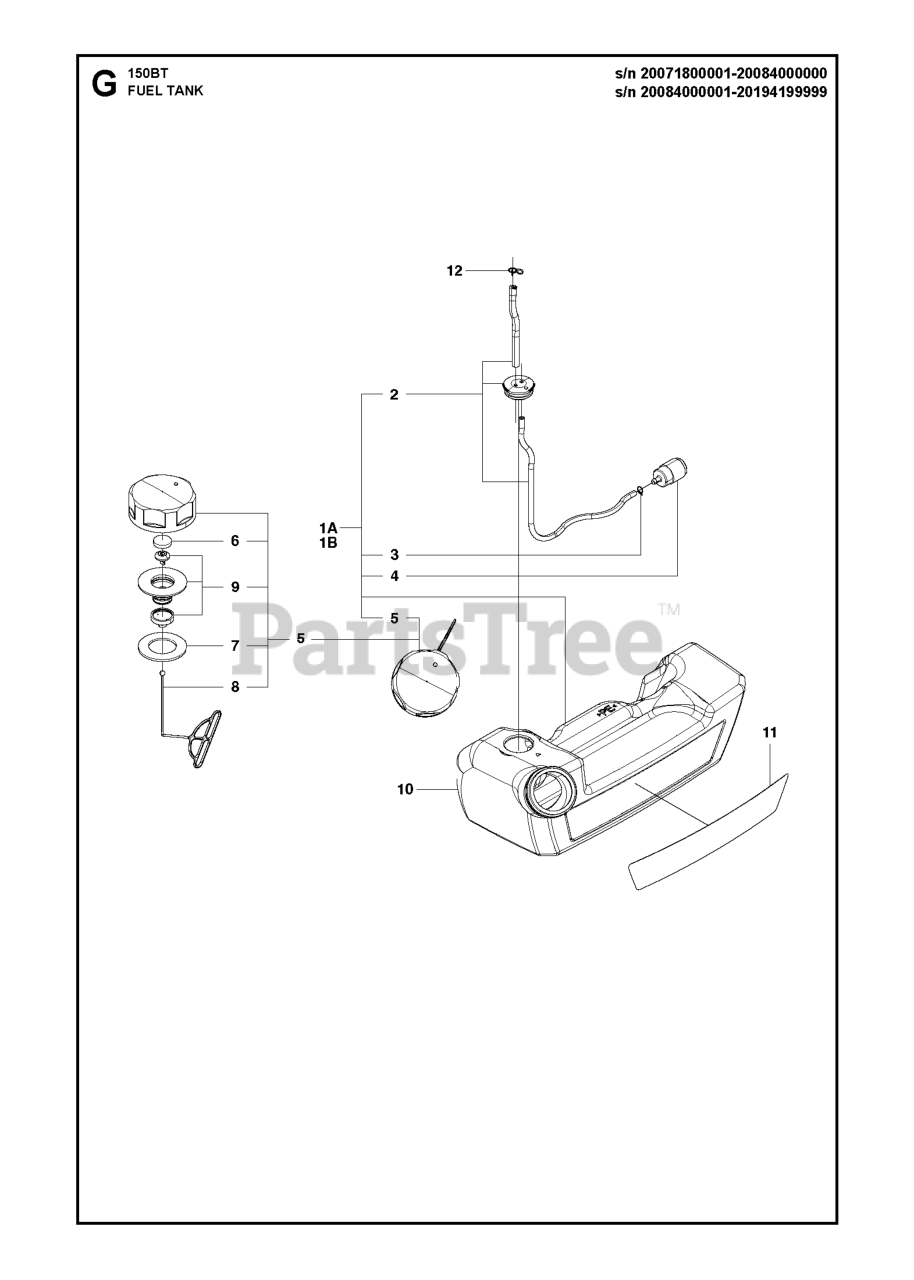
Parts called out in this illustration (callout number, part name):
1A	TANK ASSY
1B	TANK ASSY
2	PIPE C
3	CLIP
4	FILTER
5	ASSY FUEL CAP
6	FILTER
7	PACKING
9	HOLDER-A
12	CLIP
